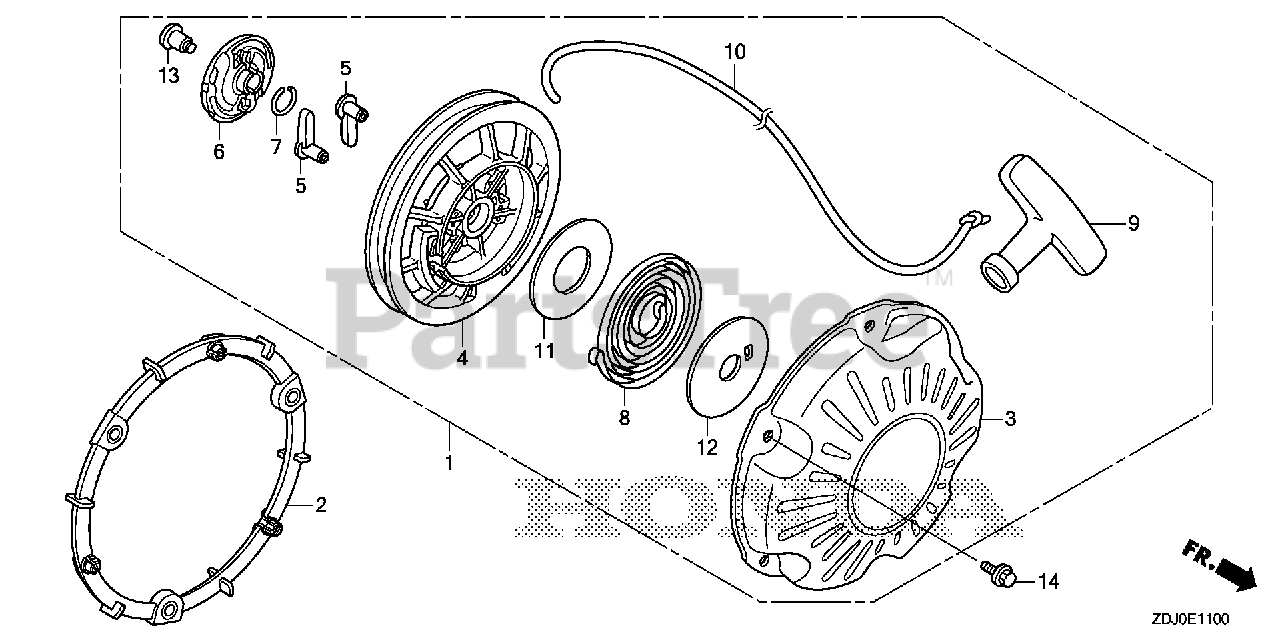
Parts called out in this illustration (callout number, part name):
1	STARTER ASSY., RECOIL *NH1* (BLACK)
2	SPACER, RECOIL STARTER MOUNTING
3	CASE, RECOIL STARTER *NH1* (BLACK)
4	REEL, RECOIL STARTER (BLACK)
4	REEL, RECOIL STARTER
5	RATCHET, STARTER
6	GUIDE, RATCHET
7	SPRING, FRICTION
8	SPRING, RECOIL STARTER
9	KNOB, RECOIL STARTER
9	GRIP, STARTER
10	ROPE, RECOIL STARTER
11	PLATE, SIDE
12	PLATE, SLIDE
13	SCREW, SETTING (ENGINE NO.)
14	BOLT, FLANGE (6X14)
